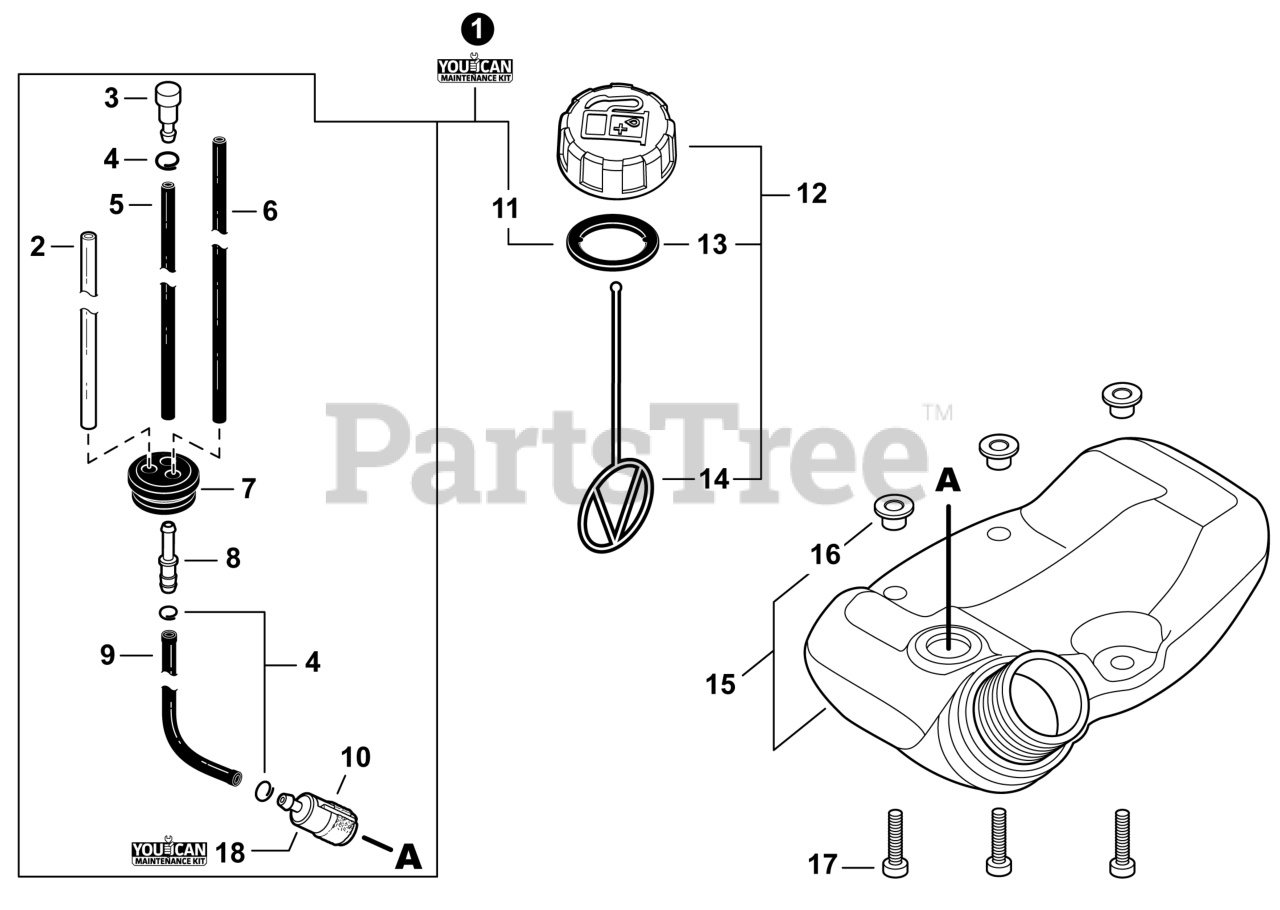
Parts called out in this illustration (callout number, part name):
1	FUEL SYSTEM KIT - YOUCANT
2	PIPE, FUEL 3x6x80 YELLOW
3	VENT ASSY
5	PIPE, FUEL 3x5x90 BLACK
6	PIPE, FUEL 3x5.5x74 BLACK
7	GROMMET, FUEL 5
8	CONNECTOR, PIPE 5x3.5
9	PIPE, FUEL 3x5x130 BLACK
10	FILTER, FUEL
11	GASKET, FUEL CAP
12	CAP ASSY, FUEL
13	GASKET, FUEL CAP
14	CONNECTOR, CAP L= 123
15	TANK ASSY, FUEL
16	COLLAR 5
17	BOLT, TORX 5x20
18	TUNE-UP KIT - YOUCANT
